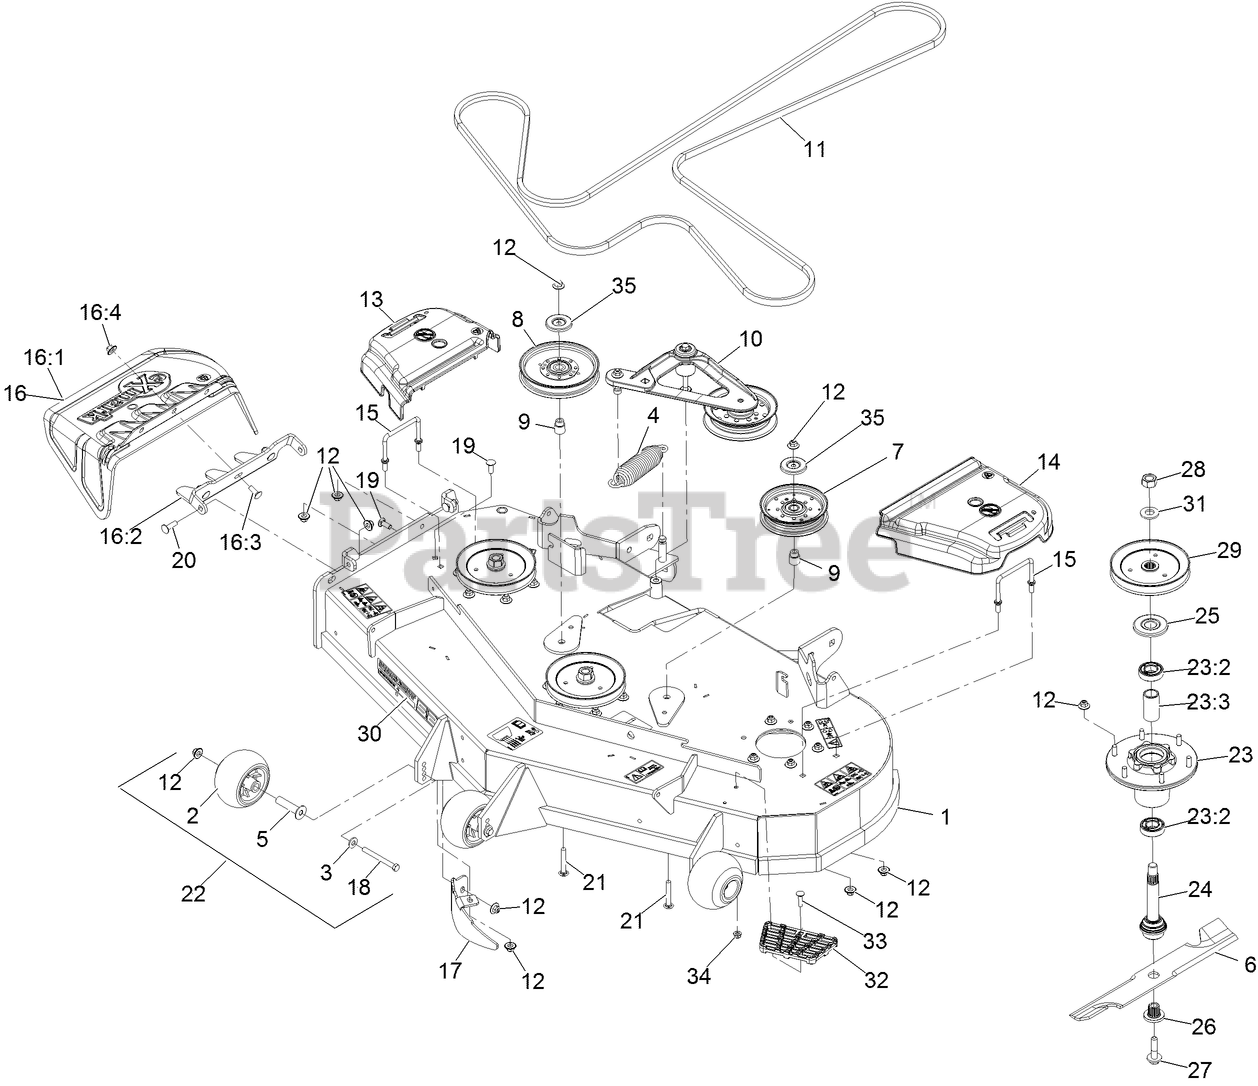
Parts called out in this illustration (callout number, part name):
1	ASM,DECK W/ DECALS 52
2	ROLLER-SCALP, ANTI
3	WASHER-BELLEVILLE
4	SPRING-EXTENSION
5	AXLE, ROLLER
7	PULLEY-IDLER, FLAT
8	IDLER-PULLEY
9	BUSHING-IDLER
10	DECK IDLER ASM
12	Nut-Nyloc 3/8-16 Flg
13	COVER-BELT, RH
14	COVER-BELT, LH
15	WIREFORM-COVER
16	ASM,DISCHARGE CHUTE
16:1	CHUTE,DISCHARGE
16:2	BRACKET,DISCHARGE CHUTE
16:3	SCREW-CARR
16:4	Nut-Nyloc 3/8-16 Flg
17	BAFFLE-DOGLEG, LZ-VT52
18	SCREW-HH 3/8-16 X 3 3/4 GR 8
19	SCREW-CARR
20	Bolt-Carriage 3/8-16 X 1 1/4
21	SCREW-CARR
22	KIT, ANTI-SCALP ROLLER
23	ASM-CUTTER HSG WITH BEARINGS
23:2	BEARING-BALL
23:3	SPACER-BEARING
24	ASM-SPINDLE AND SEAL
25	GUARD,BEARING TOP .989
26	BUSHING,SPLINED
27	SCREW,SEMS 1/2-20 X 2.19
28	NUT-HEX
29	SHEAVE,BLADE DRIVE 6.50
30	DECAL, 524
32	STEP-DECK
33	Bolt-Carriage 5/16-18 X 1 1/4
34	NUT-HF, NI
35	SHIELD-DUST
